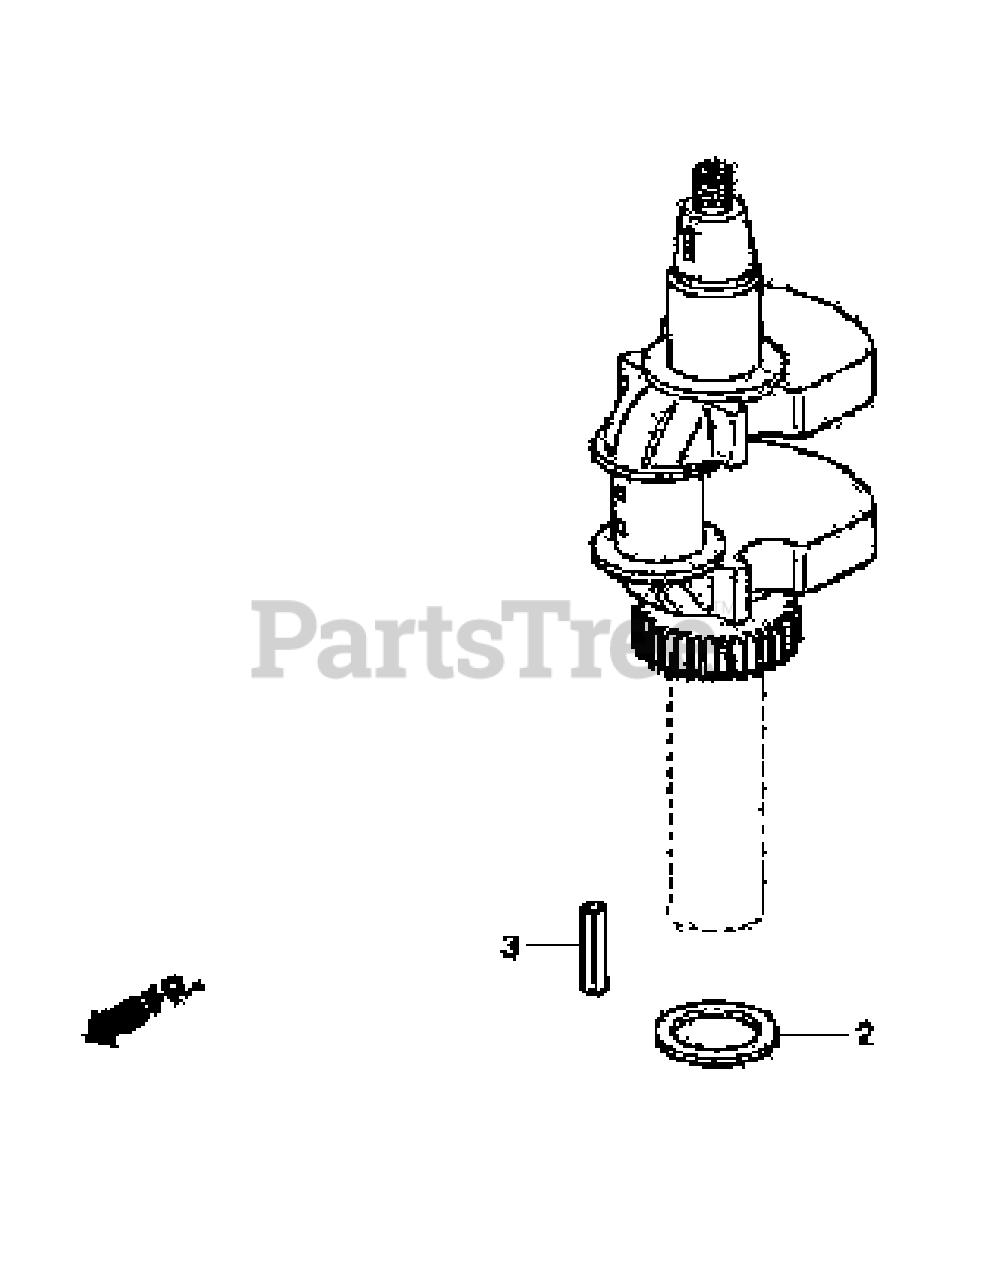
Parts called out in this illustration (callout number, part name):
1	Crankshaft
2	Crankshaft Thrust Washer
3	Key (1/4x1/4x3)
